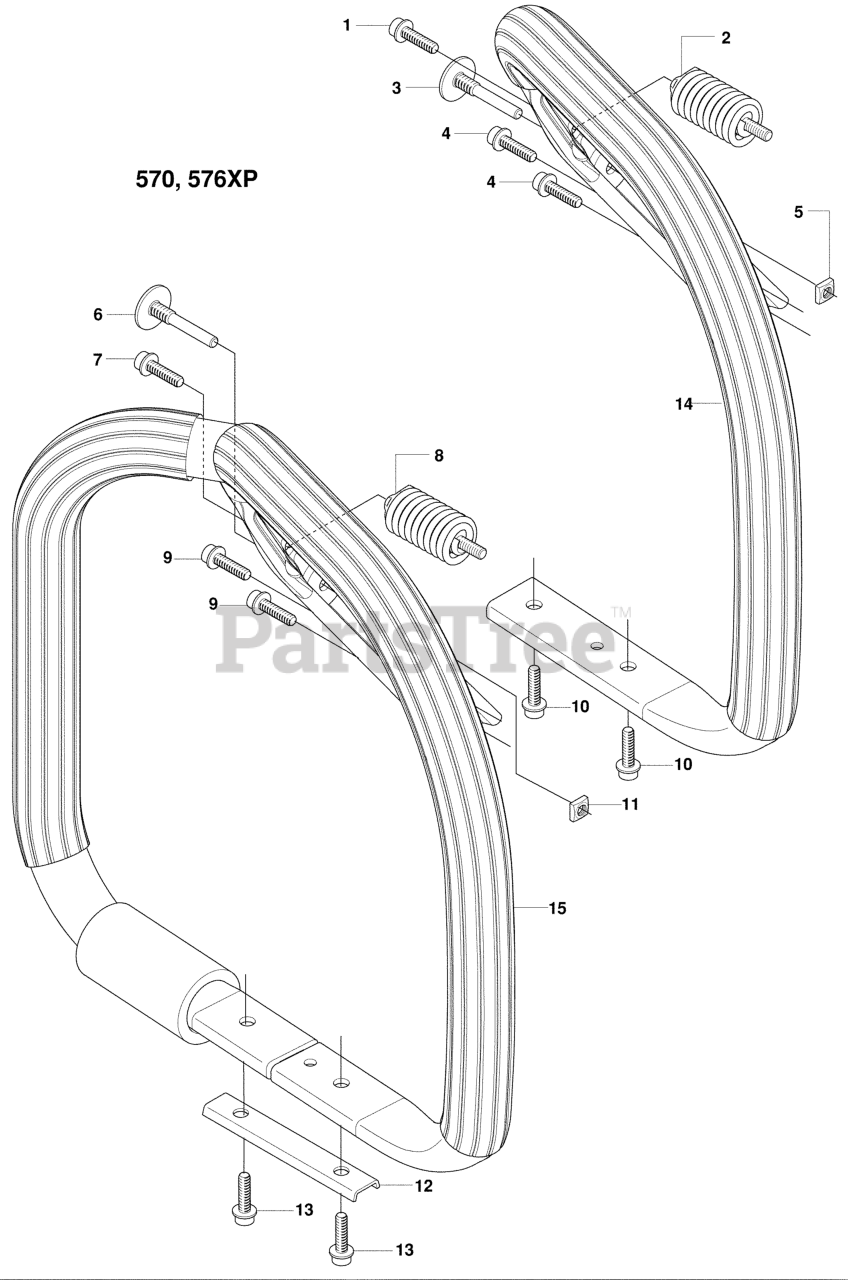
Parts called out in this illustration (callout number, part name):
2	ANTIVIBE MOUNT
8	ANTIVIBE MOUNT
14	%FRONT HANDLE
14	FRONT HANDLE ASSY
15	HANDLE
